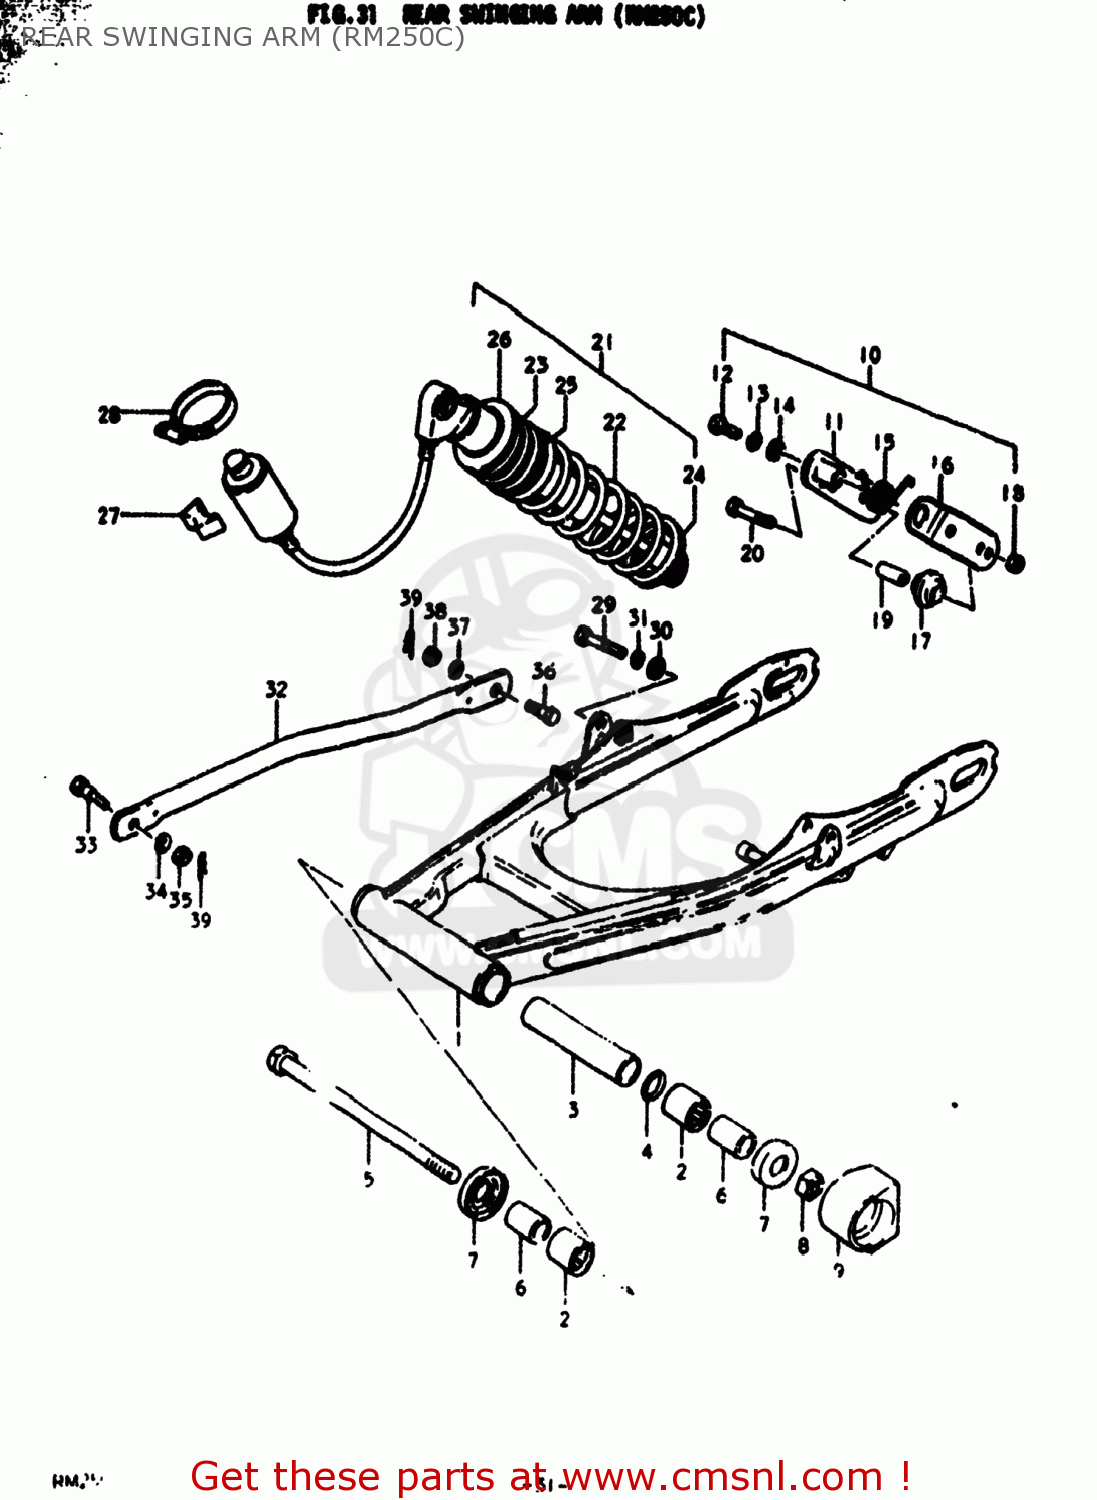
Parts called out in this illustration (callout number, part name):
1	SWING ARM ASSEMBLY,REAR
2	BEARING(20X28X25)
3	SPACER,REAR SWING ARM
4	O RING(D:1.9,ID:18.8)
5	SHAFT,REAR SWING ARM
6	SPACER(14X20X30)
7	THRUST BEARING IKO
8	NUT
9	BUFFER,CHAIN TOUCH DEFLECTOR
11	TENSIONER,CHAIN
12	BOLT
13	LOCK WASHER
14	WASHER
15	SPRING
16	PLATE,CHAIN TENSIONER
17	RUBBER,CHAIN GUARD
18	NUT 6MM
19	SPACER(6.5X10.5X22.5)
20	BOLT
21	ABSORBER ASSEMBLY,REAR SHOCK
22	SPRING
23	SPRING
25	SPRING
26	GUIDE,SPRING
27	CUSHION,RR SHOCK ABSORBER
28	CLAMP
29	BOLT 10X40
30	WASHER
31	LOCK WASHER
32	TORQUE LINK,REAR
33	BOLT(8X22.5)
34	LOCK WASHER
35	NUT
36	BOLT(10X31)
37	LOCK WASHER
38	NUT
39	CLIP
